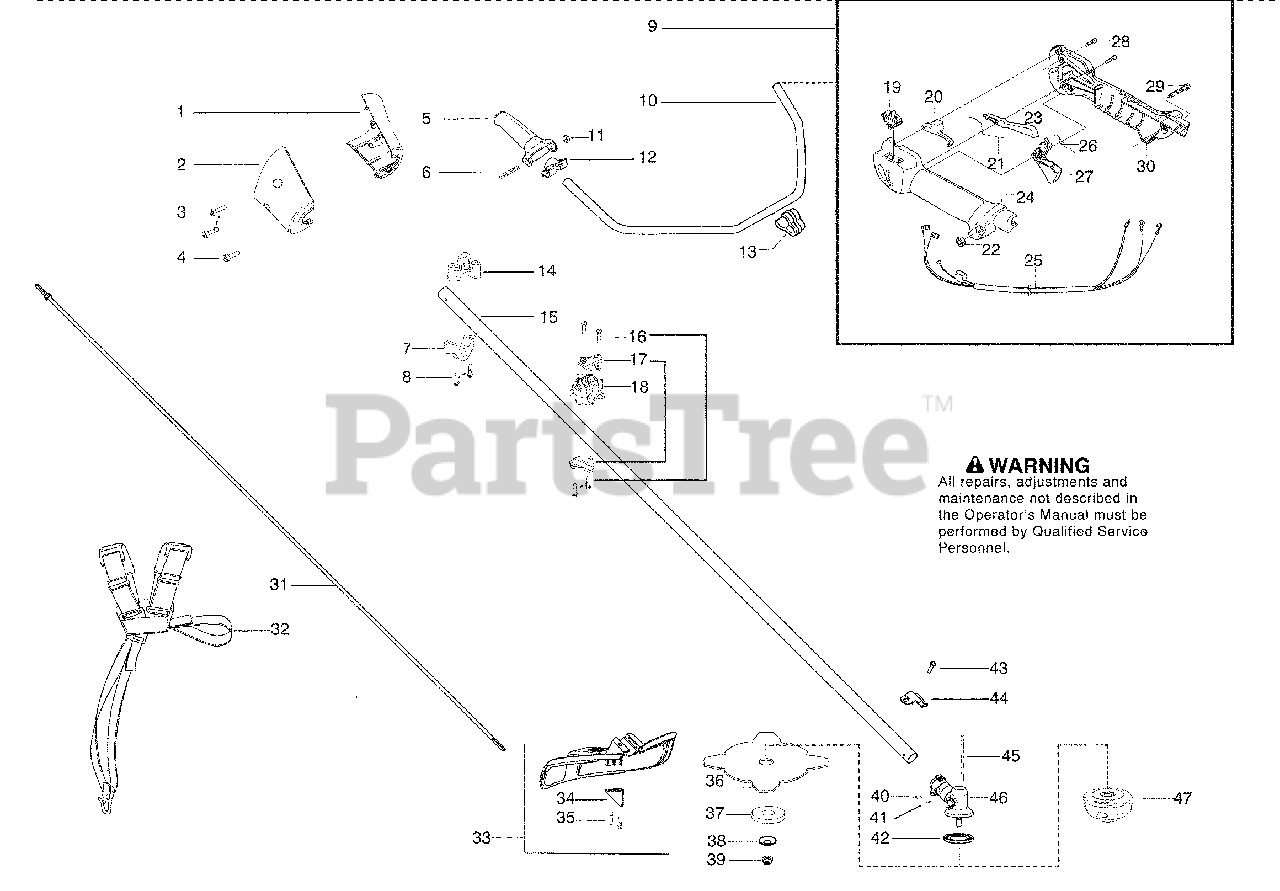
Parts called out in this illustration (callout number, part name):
1	Nose Cone - LH
2	Nose Cone - RH
5	Handle-Assist
7	Clamp-Harness
9	Assy-Throttle Housing
12	Cover-Assist Handle
13	Clip-Handlebar
14	Clamp-Harness
15	Kit-Driveshaft
17	Clamp - Bracket
18	Clamp 1" Handlebar
19	Switch-Stop
20	Lockout-Starter Throttle
21	Spring - Lockout
23	Lockout - Throttle
24	Housing - Throttle -LH
25	Assy - Cable Wire
26	Spring - Trigger
27	Trigger - Throttle
29	Screw
30	Housing-Throttle - RH
31	Flexshaft
32	Harness w/warning
33	Kit-Shield
34	Limiter - Line
36	Blade - Grass
37	Cup-Support
38	Support - Flange
39	Locknut - Blade
42	Driver Disc
44	Bracket - Shield
45	Pin - Locking
46	Assy - Gearbox
47	Assy-T25 Cutting Head
